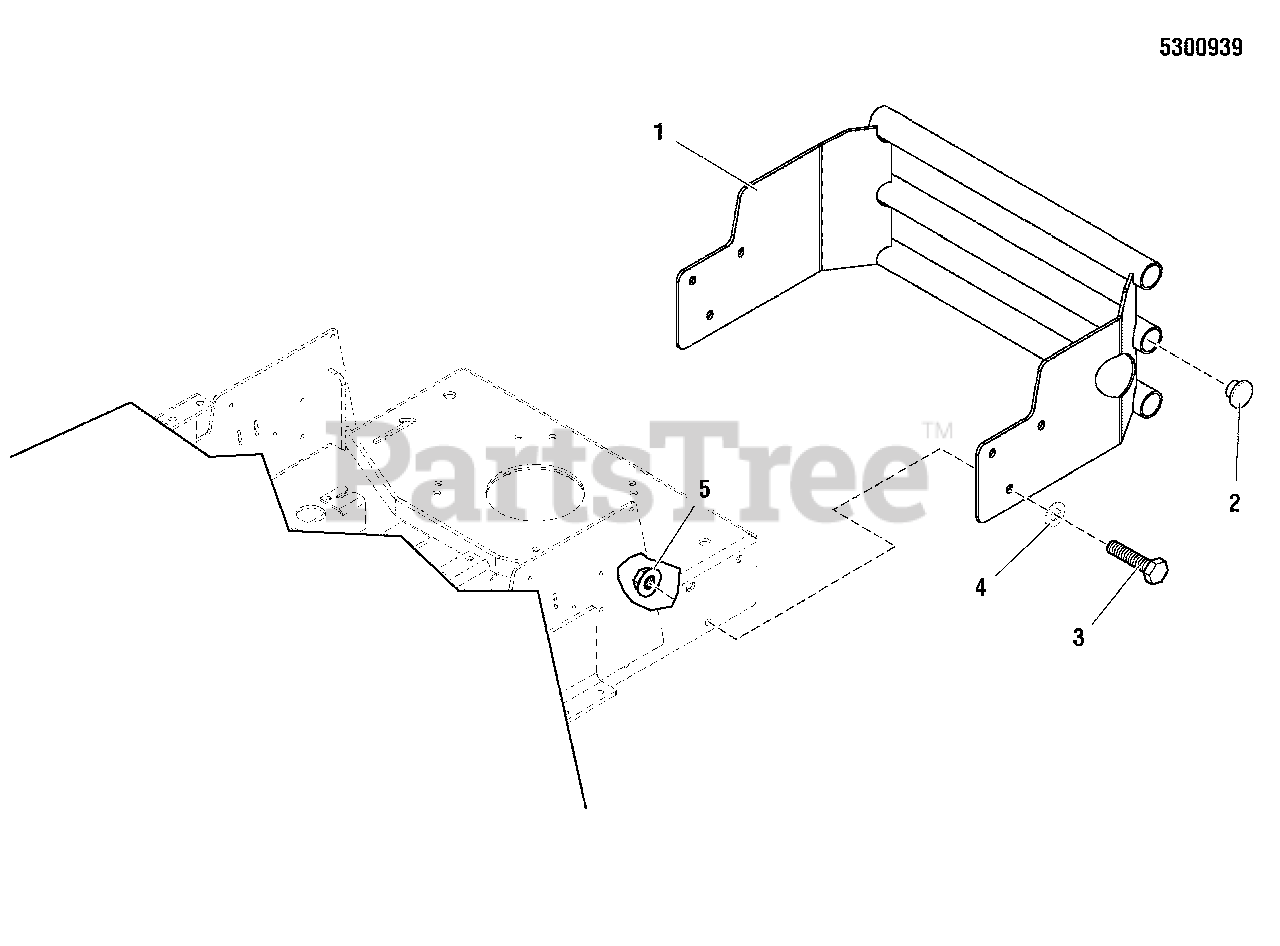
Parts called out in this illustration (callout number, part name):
1	WELD, BUMPER - CONS Z - ORG
2	PLUG, PANEL, 1.25 - BLACK
3	BOLT, 3/8-16 X 1 GD5 YZ
4	WASHER, 3/8 SAE
5	NUT, 3/8-16 HEX NYLOCK FLANGE
